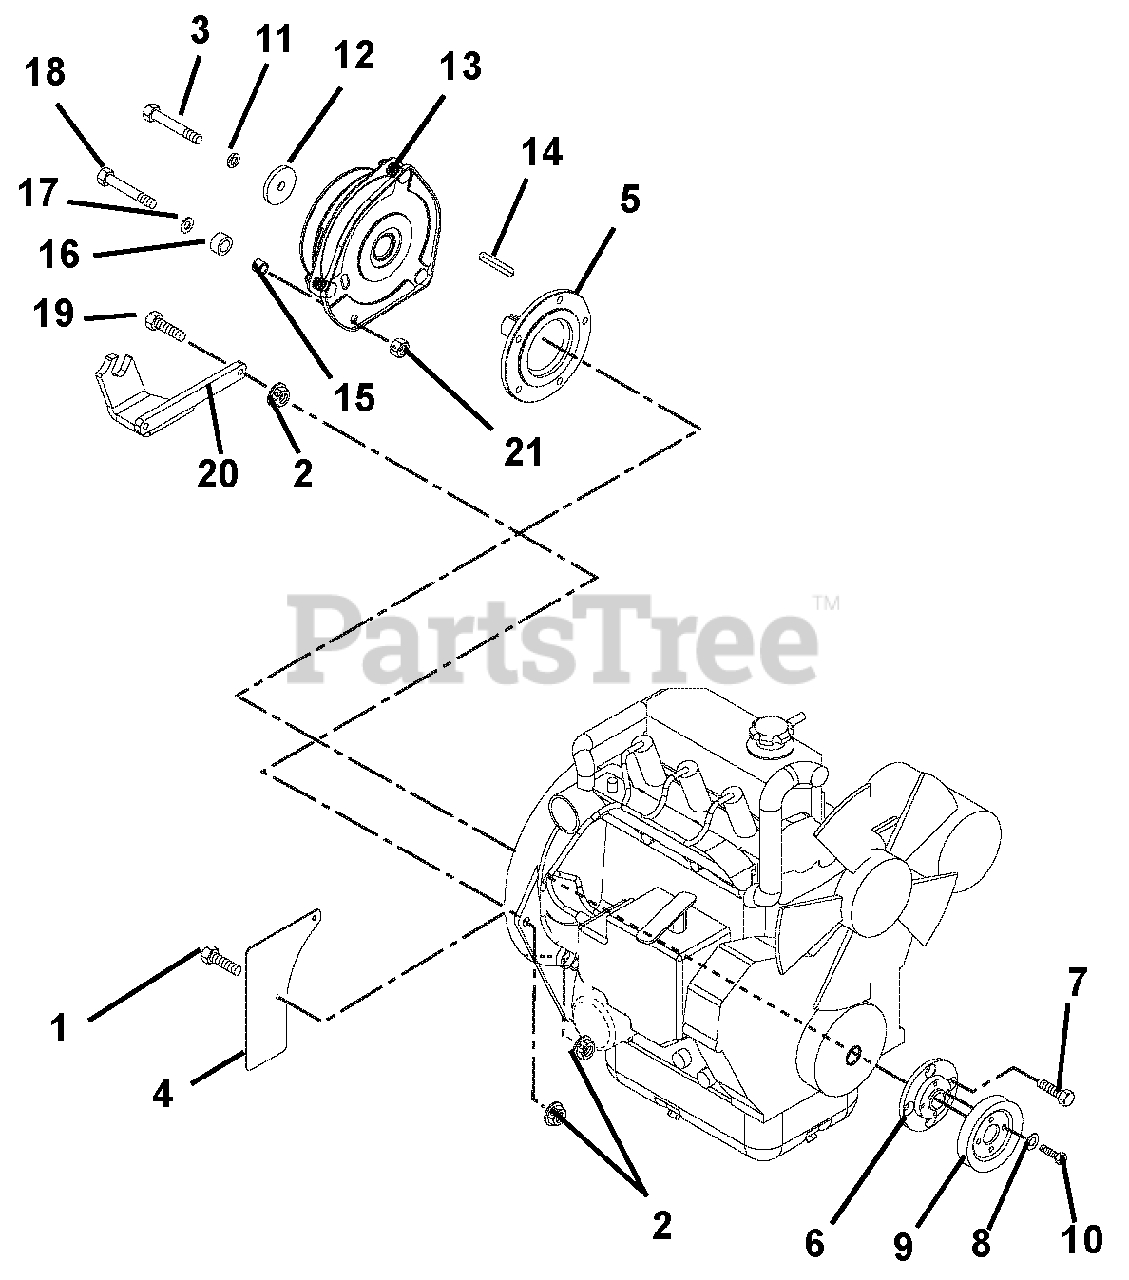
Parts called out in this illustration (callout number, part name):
1	@BLT-HEX .31-18X.75 GR5 YWZC
2	@NUT-LK-TOP-FLG .31-18 YWZC
3	BLT-HEX .44-20X2.50 G5 YZ EP80
4	GUARD, FLYWHEEL
5	SHAFT, STUB (BRIGGS-DIESEL)
6	ADAPTER, SHEAVE (DIESEL)
7	BLT, FSCHS M8-1.25X25
8	@WSHR-LK .25X.062 REG YWZC
9	SHEAVE, POLY V 1.000 X 3.25
10	@BLT-HEX .25-20X.75 GR5 YWZC
11	@WSHR-LK .44X.109 REG YWZC
12	WSHR-FL-STL .469X2.00X.25 YWZC
13	CLUTCH, OGURA GT3.5
14	KEY .25X.25X2.25
15	SPACER .375 X .625 X .500
16	BUMPER,RUBBER .62X1.0X.51 LG
17	@WSHR-FL-STL.406X.812X.065 YWZ
18	@BLT-HEX .38-16X1.00 GR5 YWZC
19	@BLT-HEX .31-18X1.25 GR5 YWZC
20	BRKT,CLUTCH STOP (DIESEL)
21	NUT-HEX-JAM .375-16 YWZC
